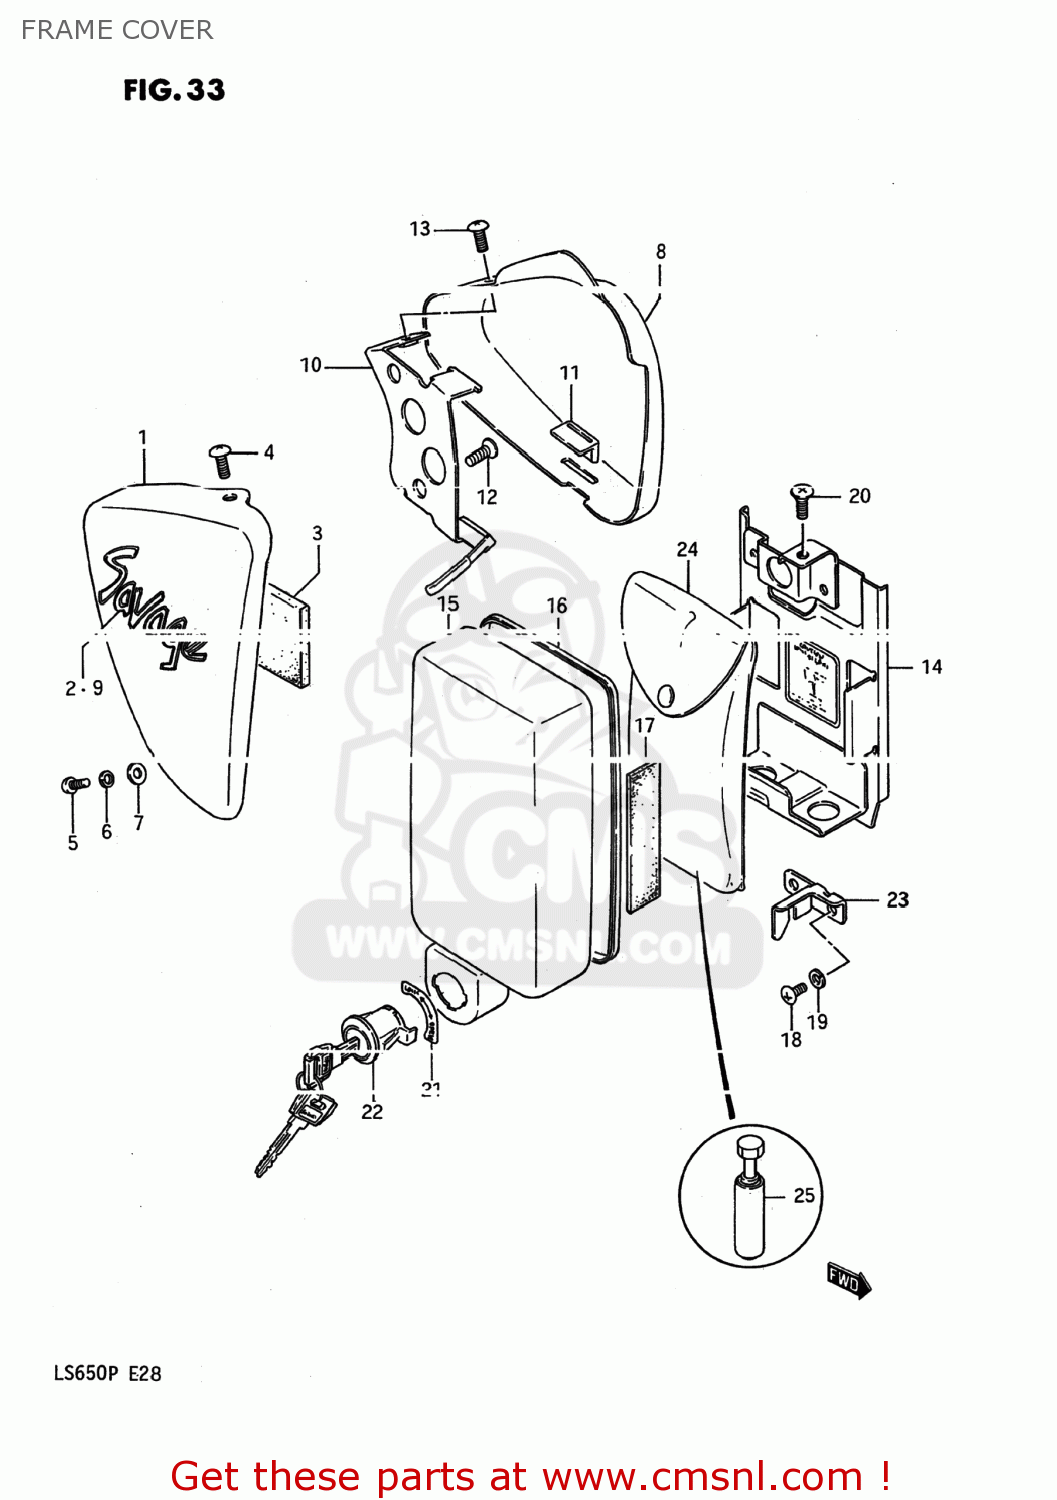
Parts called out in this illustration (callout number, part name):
1	COVER,FRAME,RIGHT
2	EMBLEM
3	PAD
4	SCREW, FRONT & REAR
5	SCREW
6	WASHER,LOCK
7	WASHER,5MM
8	COVER,FRAME,LEFT
9	EMBLEM
10	BRACKET,FRAME COVER,L
11	CUSHION,FRAME COVER
12	SCREW
13	SCREW, FRONT & REAR
14	HOLDER,TOOL
15	COVER COMP,TOOL HOLDER
16	MOLDING
17	PROTECTOR(20X90)X2
18	SCREW
19	WASHER,5MM
20	SCREW
21	LABEL,TOOL LOCK COVER
22	LOCK SET
23	PLATE,TOOL HOLDER LOCK
24	TOOL ASSY
25	GAUGE ASSY,TENSION
